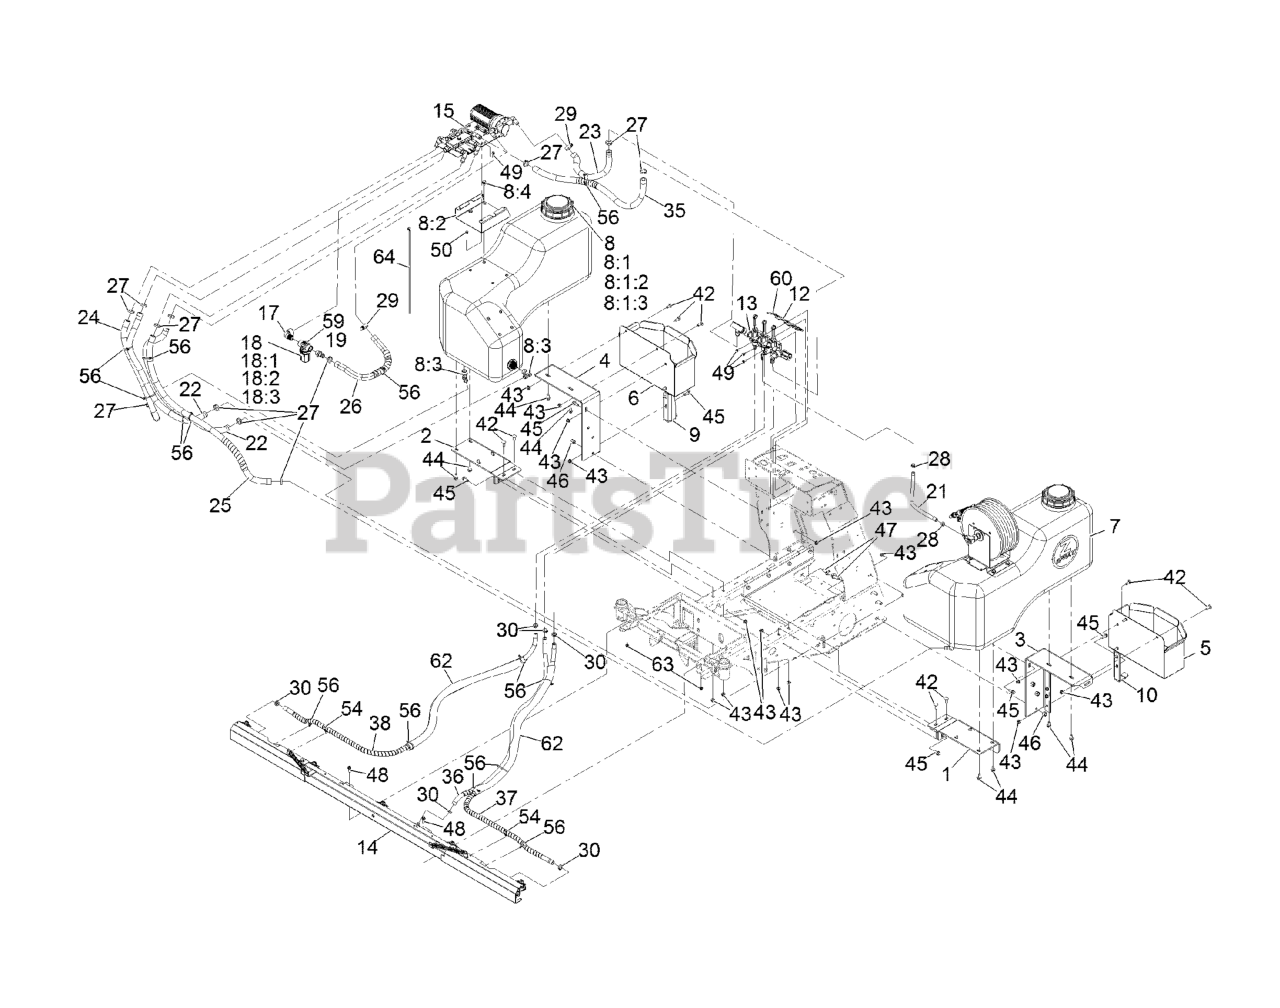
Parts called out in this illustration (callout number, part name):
1	Mount-Tank, LH Wing
2	Mount-Tank, RH Wing
3	Mount-Box, Lt Fert
4	Mount-Box, Rt Fert
5	Box-Fert, Lt
6	Box-Fert, Rt
7	ASM-Tank, Hose Reel
8	ASM-Tank, Rt
8:1	ASM-Tank, Rt
8:1:2	CAP-TANK, SPRAY
8:1:3	FITTING-BULKHEAD
8:2	PLATFORM, LIQUID VALVE MO
8:3	FITTING-ELBOW, 90
8:4	Screw-HHF
9	Bracket-Anti-Tip, Rt
10	Bracket-Anti-Tip, Lt
12	BRACKET-MANIFOLD
13	ASM-Manifold
14	ASM-Boom
15	ASM, Liquid Valve
17	ELBOW-90DEG
18	STRAINER-INLINE
18:1	BOWL-STRAINER
18:2	GASKET-HEAD, LINE STRAINE
18:3	Screen-Strainer, 50 Mesh
19	HOSEBARB
21	Hose-Spray
22	Hose-Spray
23	Hose-Spray
24	Hose-Spray
25	Hose-Spray, Wrapped
26	Hose-Spray, Wrapped
27	Clamp-Oetiker, 167
28	CLAMP-OETIKER, 167
29	CLAMP-HOSE
30	CLAMP-OETIKER, 167
35	Hose-Spray, Wrapped
36	HOSE-SPRAY, WRAPPED
37	HOSE-SPRAY, WRAPPED
38	HOSE-SPRAY, WRAPPED
42	SCREW-CARR
43	Nut-Hex Flange
44	SCREW-HHF
45	SCREW-HHF
46	Nut,1/2-13,NYL INS,ST/ST,18-8
47	SCREW-HHF
48	SCREW-HHF
49	Screw-HHF
50	Nut-Hex Flange
54	CLIP-TIE
56	TIE-CABLE
59	DECAL-CAP, STRAINER
60	Decal-Valve, Boom
62	Guard-Mesh
63	Nut-Hex Flange
64	TIE-CABLE
